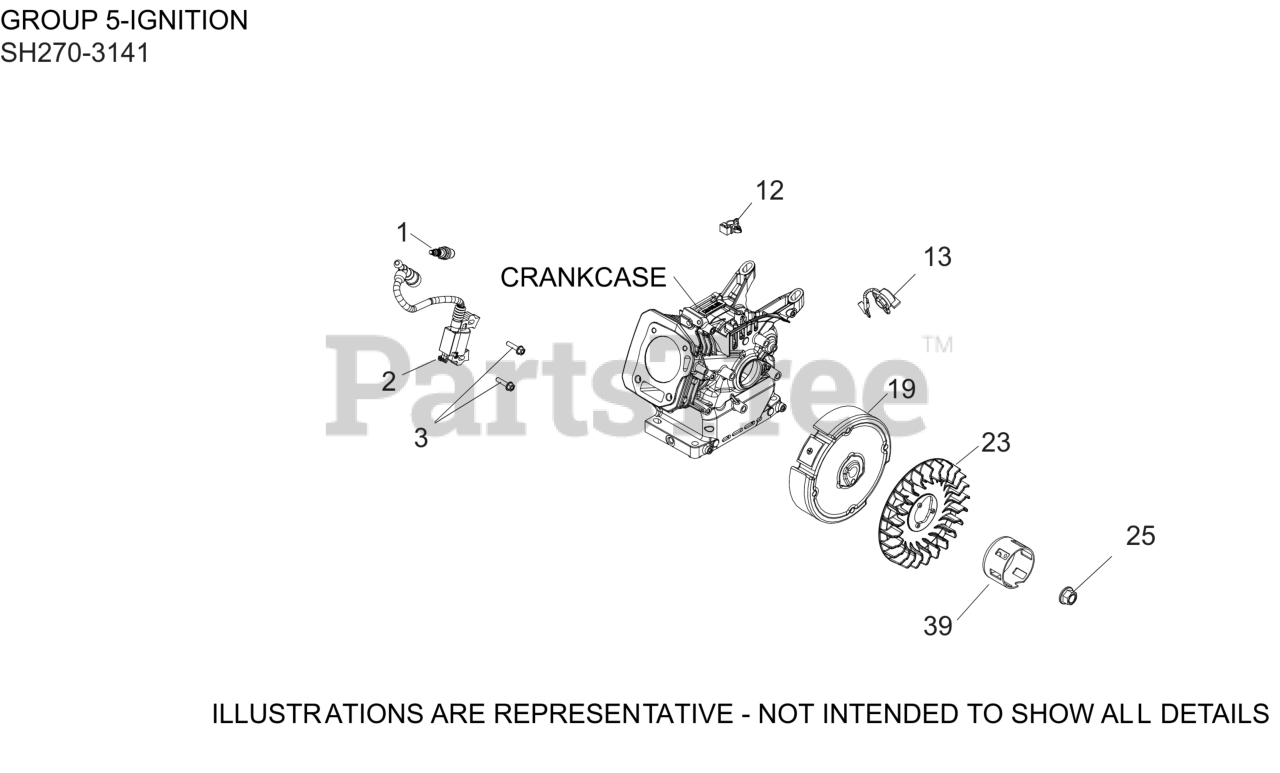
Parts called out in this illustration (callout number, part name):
1	SPARK PLUG
2	MODULE, IGNITION
3	SCREW, M6 X 25-(#25086436S)
12	CLIP, WIRE HARNESS
13	SWITCH, IGNITION
19	FLYWHEEL, ASSEMBLY
23	FAN, FLYWHEEL
25	NUT, FLYWHEEL (W/SERRATIONS)
39	STARTER CUP
